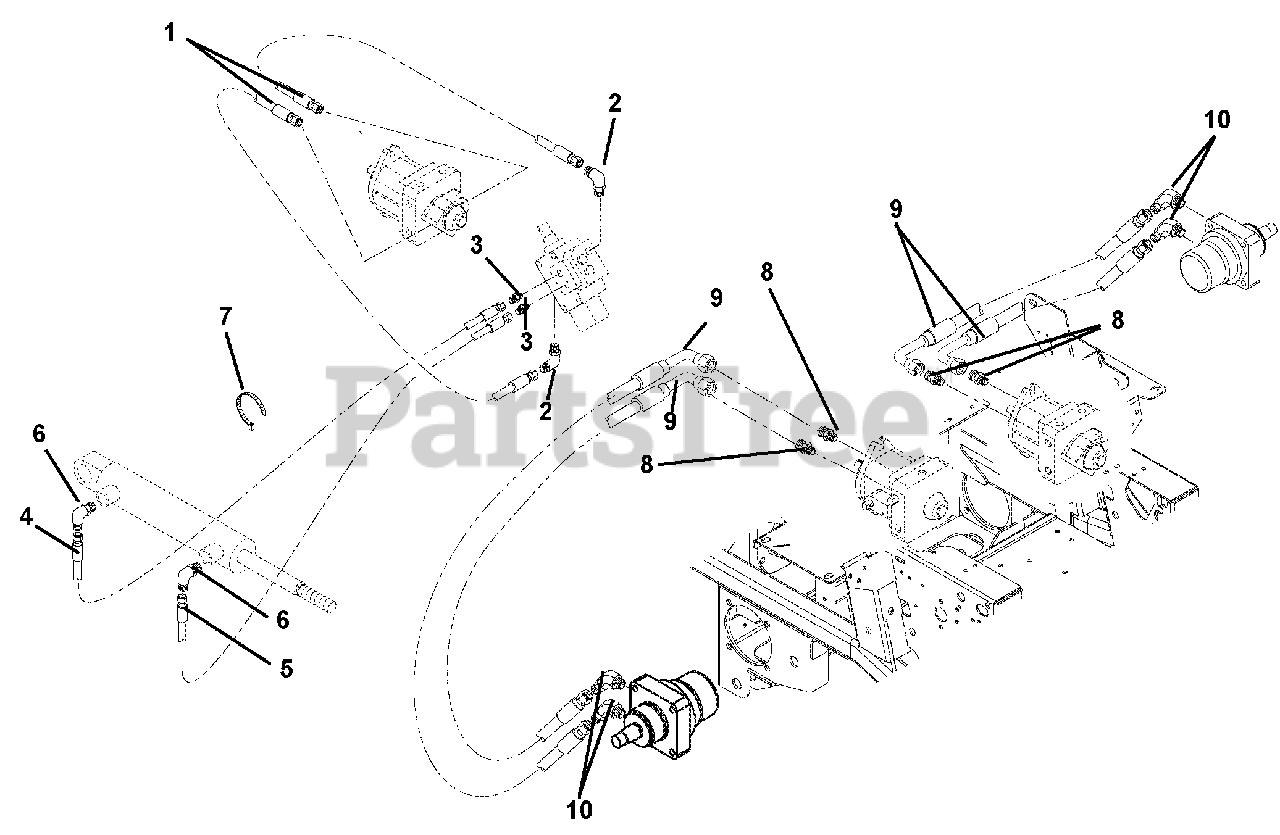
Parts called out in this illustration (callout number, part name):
1	Hose, Hydraulic
2	Hydraulic, Fitting Elbow
4	Hose, Hydraulic
5	Hose, Hydraulic
6	Fitting, Hydraulic
7	Cable Tie
8	Adapter, Face Seal 8 x 8 .50 O-Ring
9	Hose, Hydraulic .50
10	Adapter, Hydraulic Steel .875 to .75
